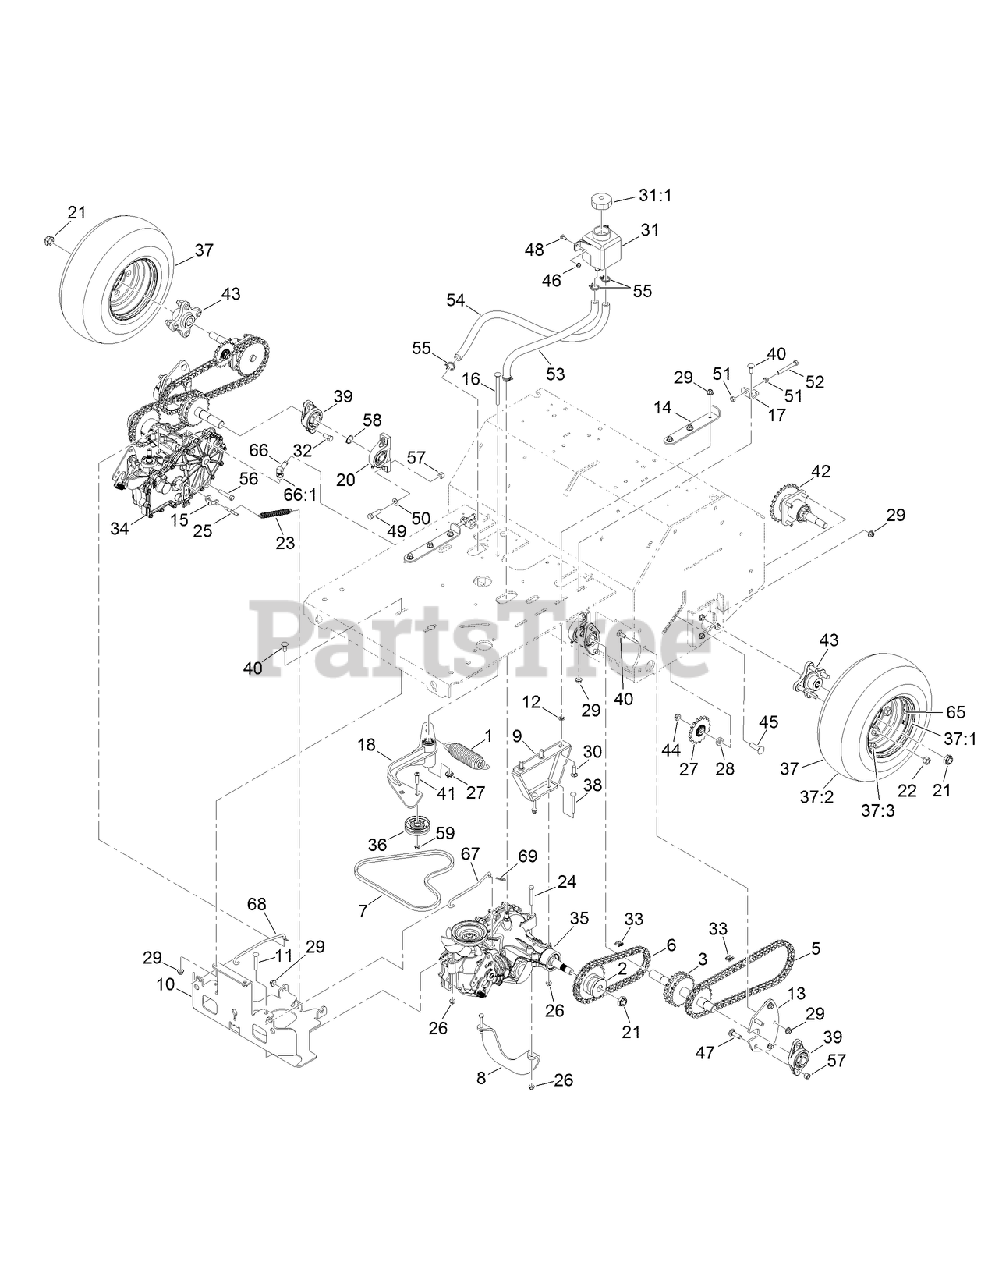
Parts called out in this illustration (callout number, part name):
1	SPRING-EXTENSION
2	HUB-DRIVE, CHAIN
3	JACKSHAFT
5	CHAIN-ROLLER
6	CHAIN-ROLLER
7	BELT-4L SECTION
8	BRACE-ANGLE
9	MOUNT-TRANSMISSION
10	GUARD-TRANSMISSION
11	BOLT-CARR
12	NUT-PUSH
13	PLATE-JACKSHAFT
14	PLATE-ADJUSTMENT, TRANSMISSION
15	YOKE-BRAKE, PARK
16	BOLT-CARR
17	BRACKET-HYDRO, ADJUST
18	IDLER ARM ASM
20	BEARING-PILLOW BLOCK
21	NUT-LOCK
22	NUT-LUG
23	SPRING-DOOR
24	SCREW-HH
25	PIN-BRAKE, PARK
26	NUT-HF, NI
27	SPROCKET-IDLER, 17T
28	WASHER
29	NUT-HF, NI
30	BOLT-CARR
31	TANK-HYD
31:1	CAP-RESERVOIR, HYD
32	SCREW-HH
33	LINK-CONNECTING
34	RH TRANSAXLE ASM
35	LH TRANSAXLE ASM
36	PULLEY-IDLER
37	WHEEL AND TIRE ASM
37:1	RIM-GRAY
37:3	STEM-VALVE
38	SCREW-CARR
39	BEARING-FLANGE, 2 BOLT
40	BOLT-CARR
41	SCREW-HSBH
42	AXLE AND BEARING ASM
43	HUB-OFFSET
44	NUT-LOCK, NI
45	SCREW-CARR
46	NUT-HF
47	BOLT-CARR
48	BOLT-CARR
49	SCREW-HH
50	WASHER-FLAT
51	NUT-HEX
52	SCREW-HH
53	HOSE-HYDRAULIC
54	HOSE-HYDRAULIC
55	CLAMP-HOSE
56	SCREW-HH
57	NUT-LOCK, NI
58	RING-RETAINING
59	NUT-LOCK, NI
65	DECAL-HUB, WHEEL
66	FITTING-ELBOW, 90
66:1	O-RING
67	LINKAGE-BYPASS, LH
68	LINKAGE-BYPASS, RH
69	PIN-COTTER
